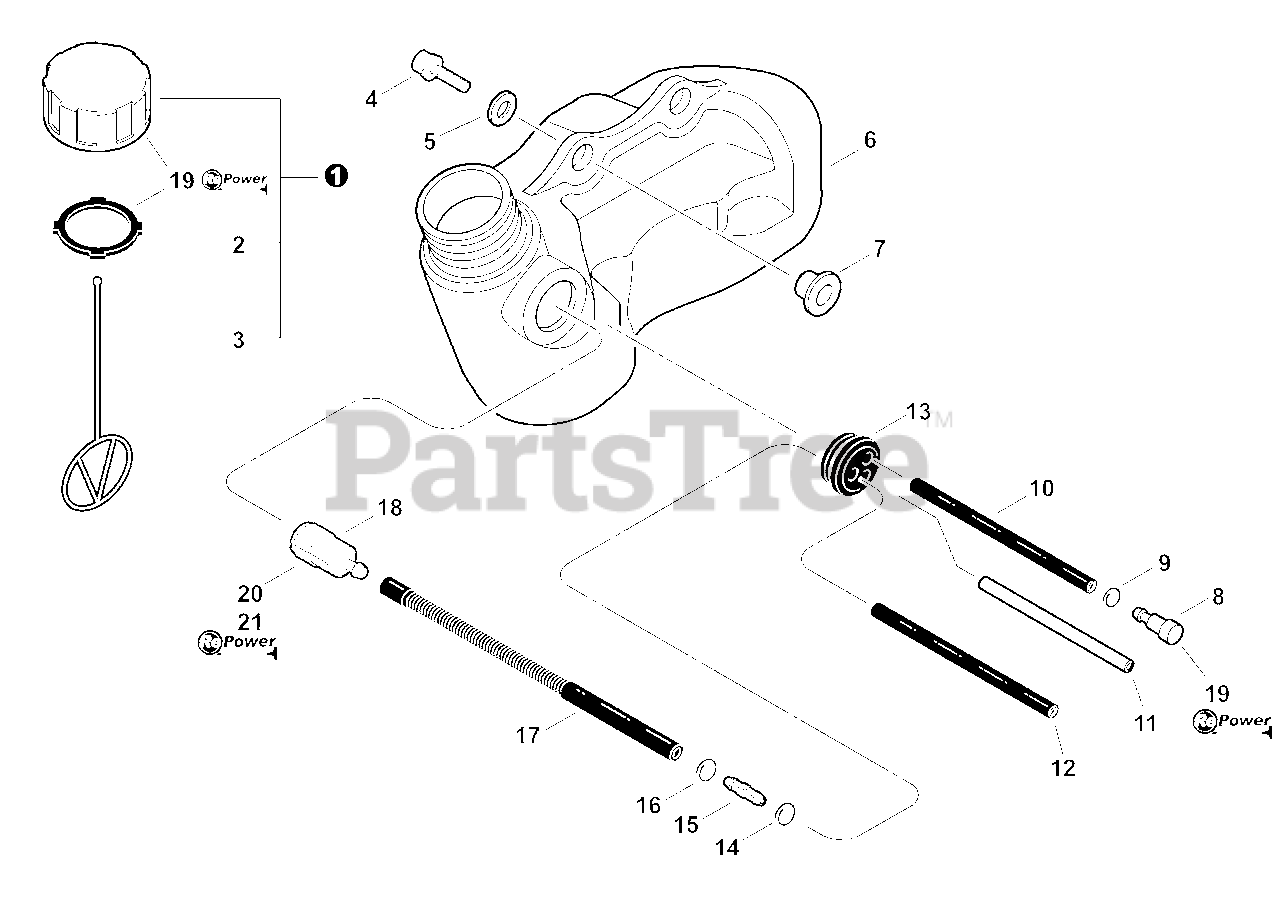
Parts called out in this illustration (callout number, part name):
1	CAP ASSY
2	GASKET, CAP
3	CONNECTOR, CAP
4	SCREW - 5×20
5	WASHER - 5
6	TANK, FUEL
8	VENT, FUEL TANK
9	CLIP - 6.6
10	PIPE - 3×6×65 -- BLACK
11	PIPE - 3×6×75 -- CLEAR
12	PIPE - 3×6×105 -- BLACK
13	GROMMET
14	CLIP - 6
15	CONNECTOR, PIPE
16	CLIP - 6.5
17	PIPE, FUEL - CORRUGATED
18	FILTER, FUEL
19	Repower CAP AND VENT KIT
20	RePower FILTER KIT
21	RePower TUNE-UP KIT
